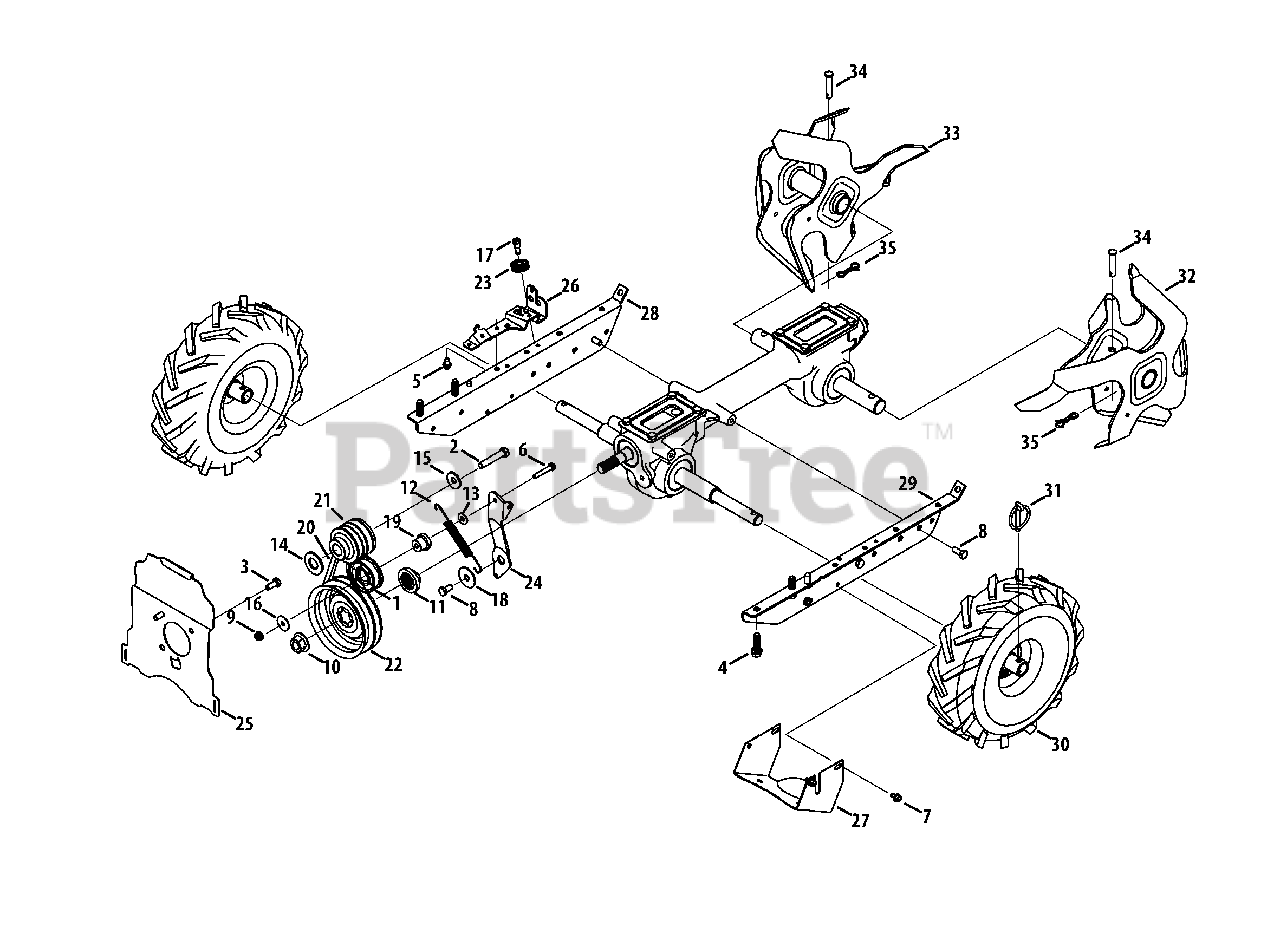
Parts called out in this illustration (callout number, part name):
1	Idler Pulley Assembly
2	Hex Head Screw, 3/8-24 x 2.00
3	Hex Head Screw, 5/16-24 x .625
4	Hex L-Washer TT-Tap, 3/8-16 x 1.25"
5	Self Tapping Screw, 1/4-20 x .500
6	Hex Head Screw, 1/4-20 x 1.50
7	Self Tapping Screw, 1/4-14 x .625
8	Hex Head Screw, 5/16-18 x .75, Patch
9	Nylon Hex Lock Nut, 1/4-20
10	Nut, 9/16-18, Flange Lock
11	Hub, 5/8 Spline
12	Extension Spring, .480 OD X 5.00 LG
13	Washer, .28 x .74 x .063
14	Washer, Flat, .760 x 1.50 x .120
15	Bell Washer, .396 x 1.140 x .095
16	Flat Washer, .265 x 1.0 x .030
17	Shoulder Screw, .342 x .335 1/4-28
18	Pivot Idler Spacer
19	Shoulder Spacer, .260 x .785 x .538
20	V-Belt, 4L x 25.375 Long
21	Engine Pulley
22	Transmission Pulley
23	Cable Roller
24	Idler Bracket, Forward
26	Pulley Bracket
27	Pulley Shield
28	Mounting Frame, RH
29	Mounting Frame, LH
30	Wheel Assembly, 11 x 4 x 4
32	Tine Assembly, LH
33	Tine Assembly, RH
34	Clevis Pin, .375 x 1.75
35	Cotter Pin, Bow Tie
